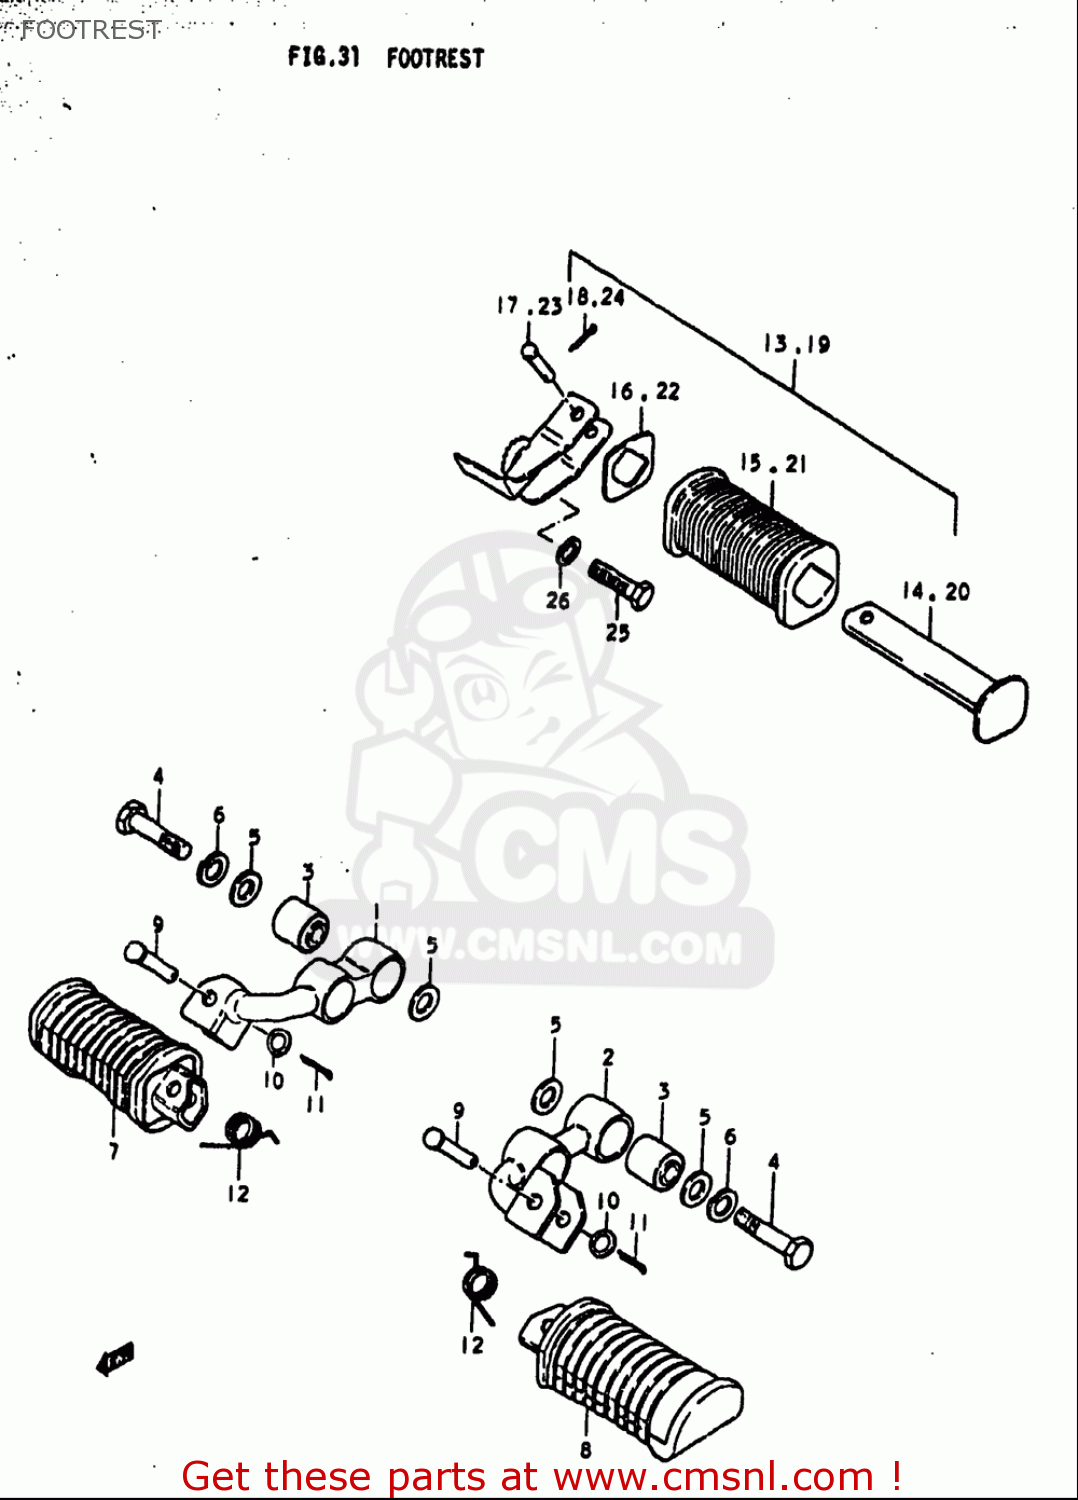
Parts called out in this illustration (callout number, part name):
2	BAR,FRONT FOOTREST,LEFT
3	BUSH
4	BOLT(10X38)
5	WASHER(10.5X20X2.3)
6	WASHER,LOCK
7	RUBBER,PILLION FOOTREST,R
8	RUBBER,PILLION FOOTREST,L
9	PIN
10	WASHER
11	PIN
12	SPRING
15	RUBBER,PILLION FOOTREST
16	WASHER,PILLION FOOTREST RUBBER
17	PIN
18	PIN
21	RUBBER,PILLION FOOTREST
22	WASHER,PILLION FOOTREST RUBBER
23	PIN
24	PIN
25	BOLT
26	WASHER,LOCK
